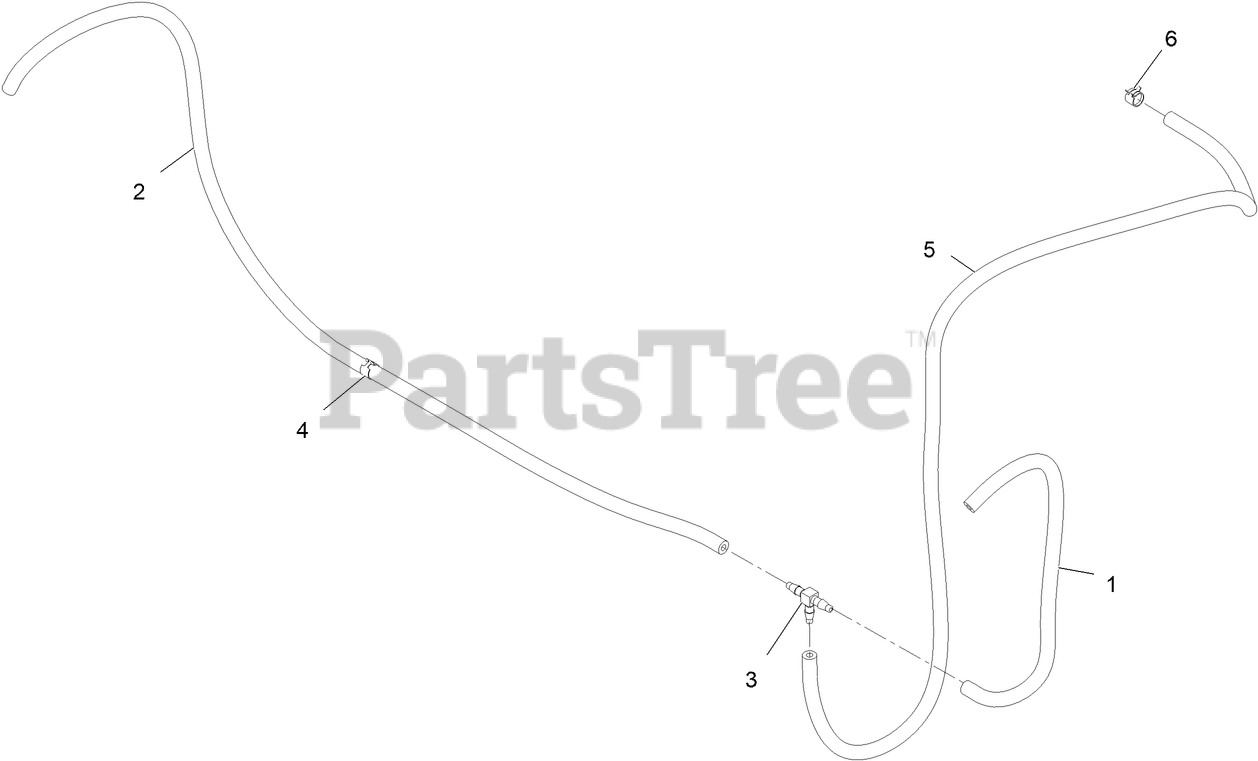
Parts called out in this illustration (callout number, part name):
1	HOSE-FUEL
2	HOSE-LP
3	FITTING-TEE
4	Clamp Hose
5	Hose-Fuel
6	CLAMP-HOSE
